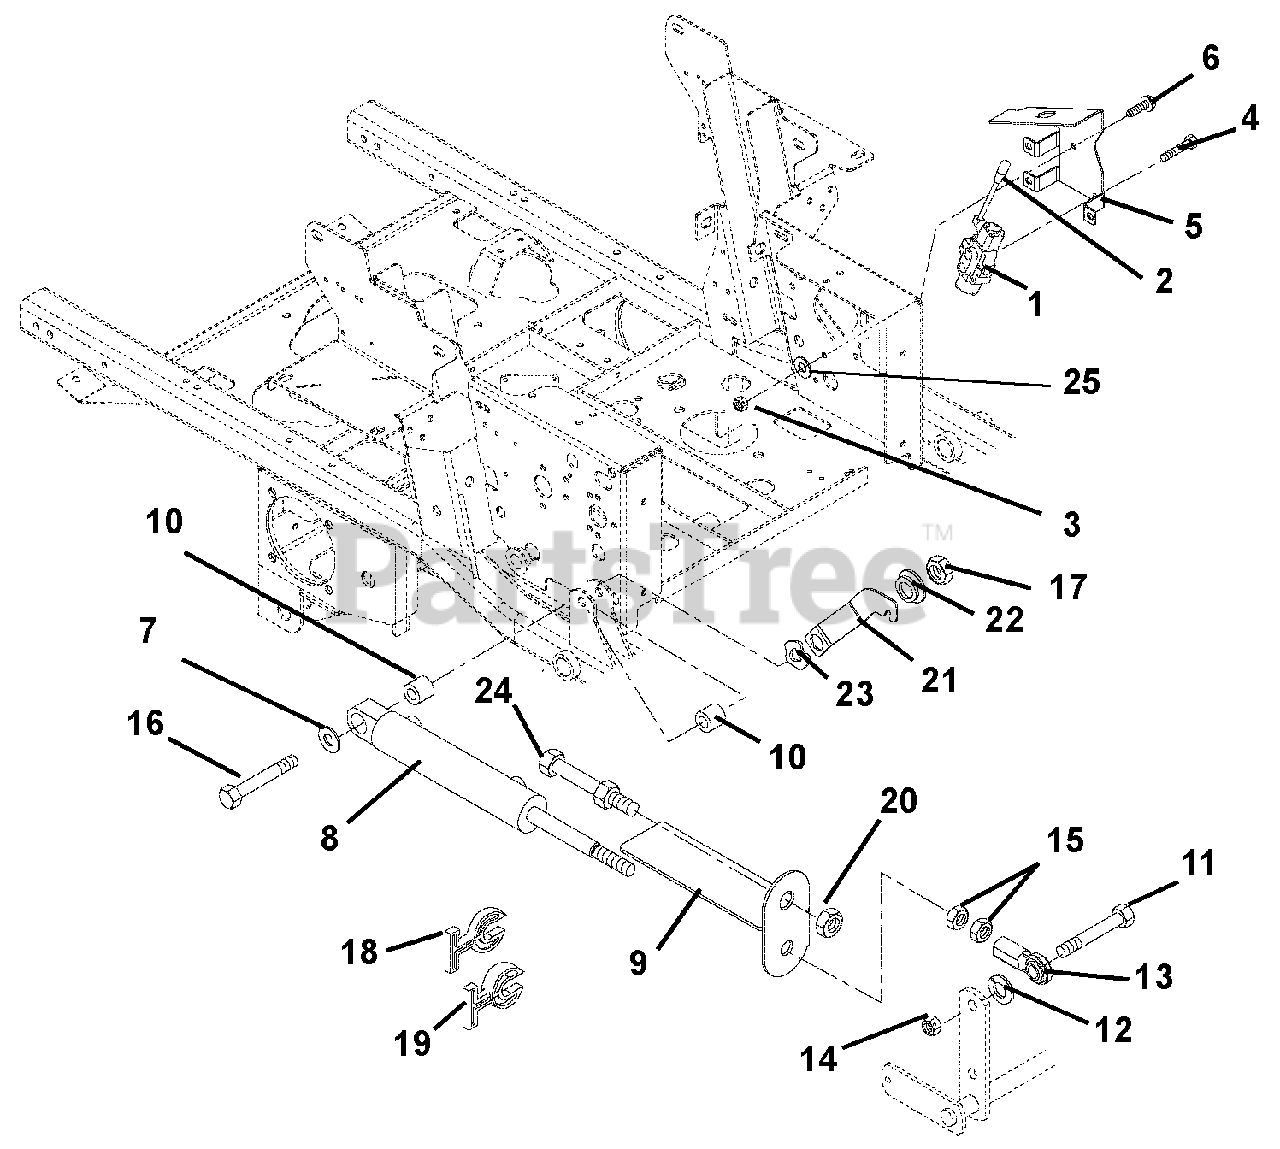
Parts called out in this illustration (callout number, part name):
1	Valve, Hydraulic Lift
2	Knob (Service Only)
3	Nut, Locking Center .31-18
4	Bolt, Hex .31-18 x 2.0 Grade 5
5	Bracket, Valve Mounting
6	Screw, Tapping .38-16 x .50 Hex Washer Head
7	Washer, Flat Steel .515 x 1.625 x .25
8	Cylinder, Hydraulic Lift
9	Strap, Cut Indicator / Guard
10	Bushing .516 x 1.00 x 1.05
11	Bolt, Hex .62-11 x 2.25 Grade 8
12	Washer, Lock .62 x .156
13	Rod End, Right Hand Female .625
14	Nut, Locking Center .62-11
15	Nut, Jam .625-18
16	Bolt, Hex .50-13 x 3.75 Grade 5
17	Nut, Locking Top Flange .50-13
18	Stop, Cylinder .34 Thick
19	Stop, Cylinder .68 Thick
20	Nut, Jam .75-16
21	Latch, Footboard
22	Bushing, Flange .515 x .75 x .275 x 1.12
23	Washer, Wave .076 x 1.12 x .08
25	Washer, Locking .31 x .078 Regular
